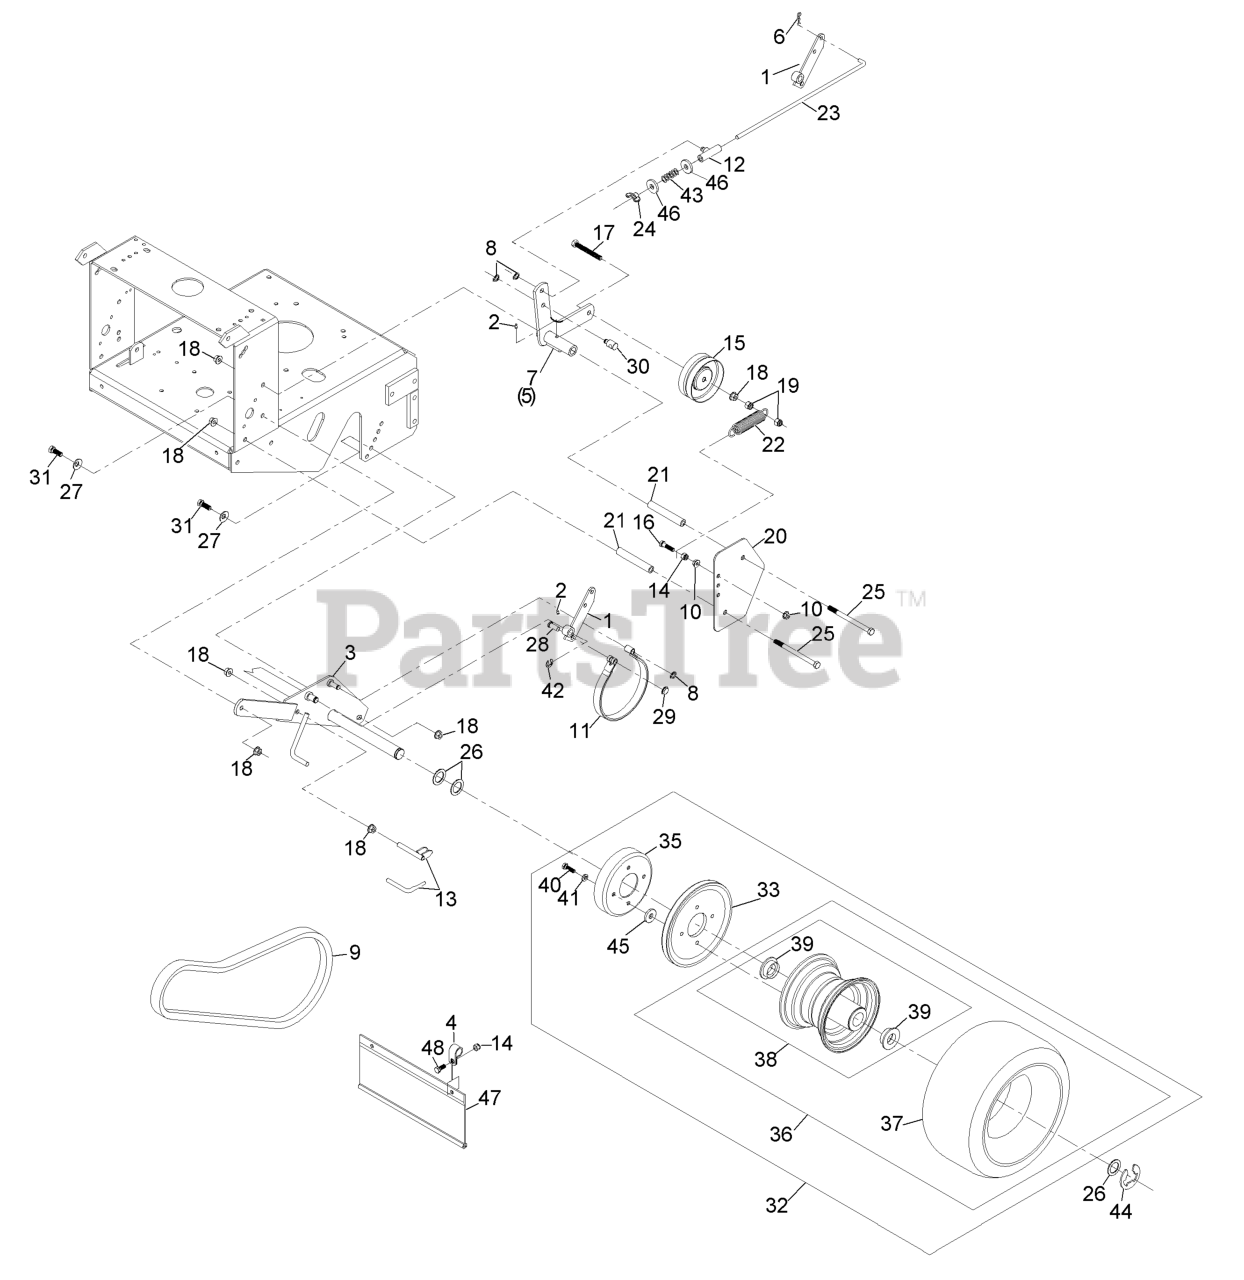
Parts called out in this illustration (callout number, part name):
1	ARM-BRAKE
2	FITTING-GREASE
4	CLAMP-R
5	ARM-IDLER, LH
6	PIN-COTTER
7	ARM-IDLER, RH
8	RING-RETAINING
9	BELT-WHEEL, DRIVE
11	BAND-BRAKE
12	SWIVEL-BRAKE
13	SCRAPER
14	NUT-LOCK, NI
15	IDLER-WHEEL, DRIVE
16	SCREW-HH
17	SCREW-HH
18	NUT-HHF, WHIZ
19	NUT-LOCK, NI
20	SHIELD-WHEEL, DRIVE
21	SPACER-SHIELD
22	SPRING-EXTENSION
23	LINKAGE-BRAKE
24	WINGNUT-NYLOCK
25	SCREW-HH
26	WASHER-SPACER
27	WASHER-BELLEVILLE
28	PIN-CLEVIS
29	RING-RETAIN,PUSH,EXT,FLAT
30	SWIVEL-LEVER, DRIVE
31	SCREW-HH
32	DRIVE WHEEL ASM
33	SHEAVE-WHEEL, DRIVE
35	DRUM-BRAKE
36	WHEEL AND TIRE ASM
38	WHEEL AND HUB ASM
39	BEARING-FLANGED
40	SCREW-HH
41	WASHER-LOCK
42	RING-RETAINING, EXTERNAL
43	SPRING-COMPRESSION
44	RING-SNAP
46	WASHER-PLAIN
47	SHIELD-TRAILING
48	SCREW-HH
